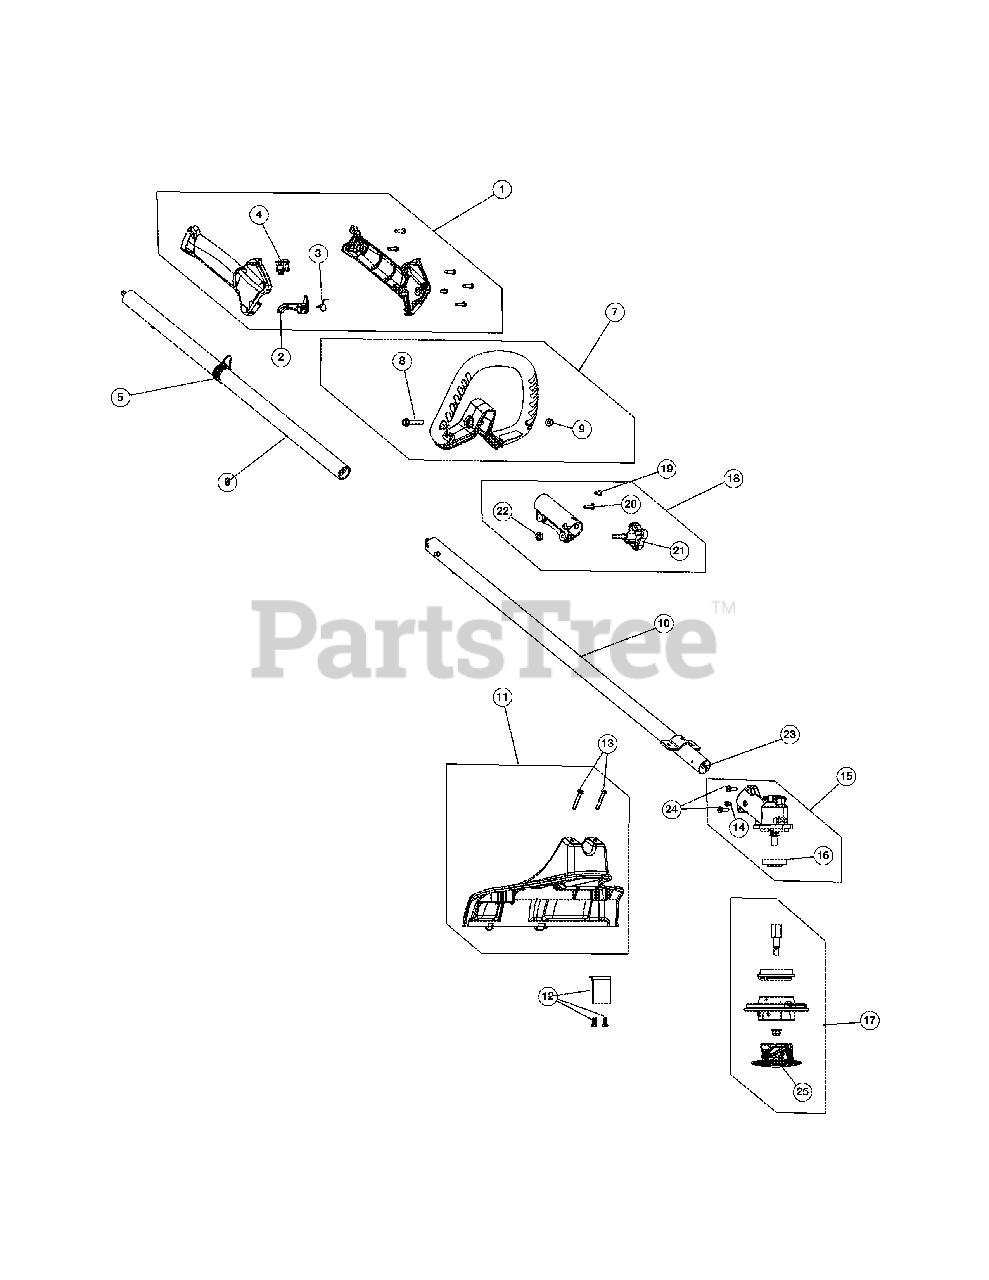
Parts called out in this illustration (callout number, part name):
1	Throttle Housing Assembly (Incl Ref No. 2-4)
2	Throttle Trigger
5	Shoulder Strap Clip
6	Upper Drive Shaft Housing Assembly
7	D-Handle Assembly (Incl Ref No. 8 & 9)
10	Lower Drive Shaft Housing Assembly
11	Shield Assembly (Incl Ref No. 13)
12	Blade Assembly
14	Anti-Rotation Screw
15	Gear Box (Incl Ref No. 14, 16 & 24)
16	Gear Box Spacer
17	Cutting Head Assembly (Incl Ref No. 25)
18	Split Boom Coupler (Incl Ref No. 19-22)
21	Adjustment Knob
22	Knob Retaining Nut
23	Lower Flexible Drive Shaft
24	Gear Box Screw
25	Cutting Head Cap
